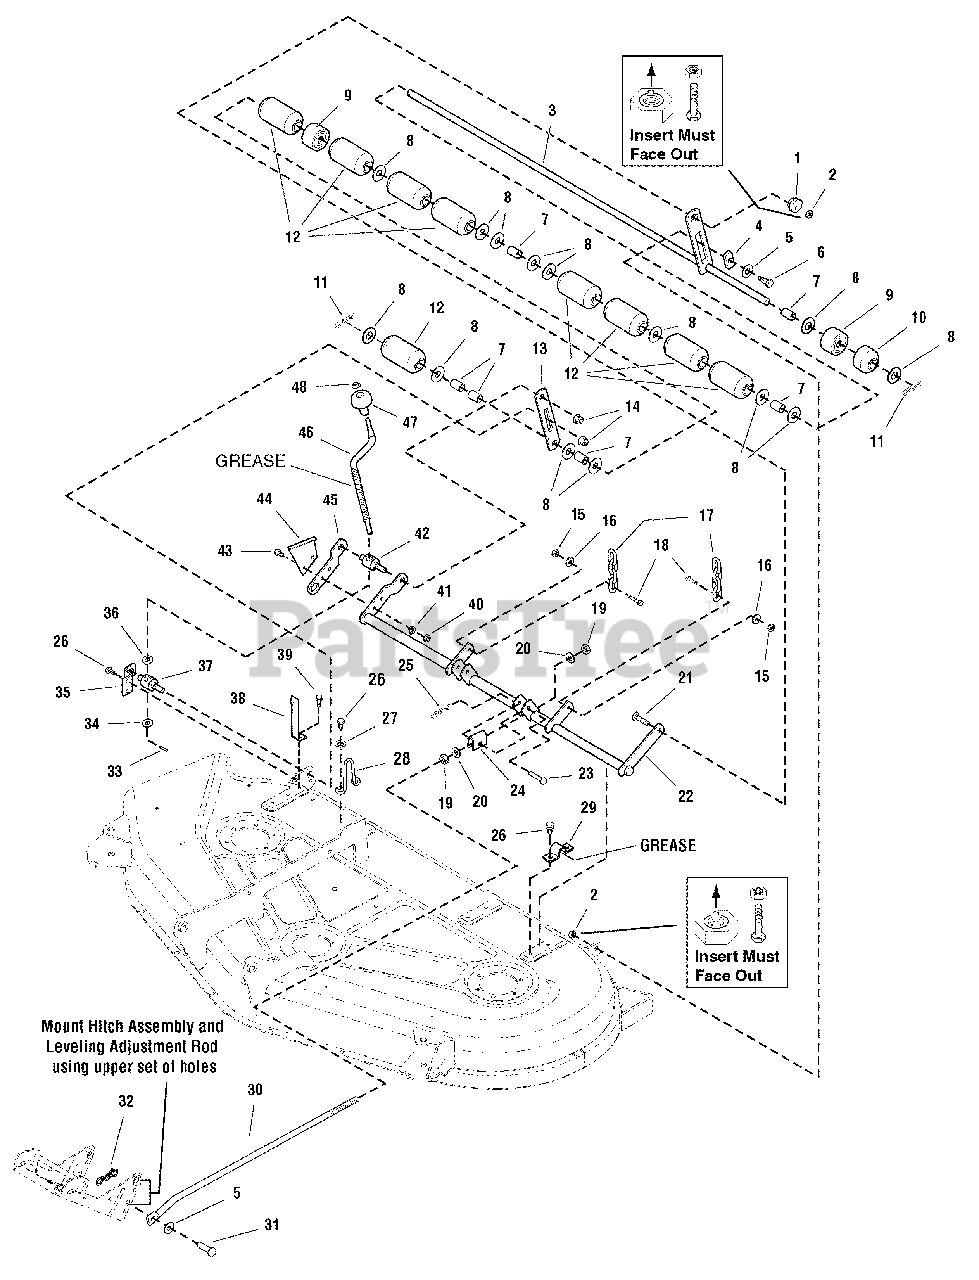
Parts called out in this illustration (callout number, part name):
1	NUT, Hex, Adjusting
2	NUT, Hex Aluminum Insert Lock, 3/8-16
3	SHAFT & BAR ASSEMBLY, Roller
4	SLIDE
5	WASHER, 1/2
6	BOLT, Shoulder, 3/8-16 x 1-5/16
7	SPACER
8	WASHER
9	ROLLER, 1 x 2-3/4 x 2, Black
10	ROLLER, Half Rounded
11	PIN, Cotter, 1/8 x 1-1/2, Black
12	ROLLER, with Bushings, Full
13	BAR
14	NUT, Hex Flange, 1/2-13
15	NUT, Hex Lock ESNA Light, 5/16-18
16	WASHER, 5/16
17	CHAIN, 4 Links, 6" Long
18	CAPSCREW, Hex Head, 5/16-18 x 1-1/2, G8
19	NUT, Hex, 5/8-11
20	WASHER, 5/8
21	CARRIAGE BOLT, 3/8-16 x 1-1/2
22	ASSEMBLY, Rocker Shaft
23	PIN, Round Head, 3/8 x 2
24	TRUNNION
25	CLIP, Hair Pin
26	CAPSCREW, Hex Washer Head, Taptite, 5/16-18 x 3/4
27	WASHER, 5/8
28	UP-STOP, Wire
29	STRAP
30	ROD, 5/8 x 29-5/8 Long
31	PIN, Yoke, 1/2
32	PIN, Bow Tie
33	PIN, Roll
34	WASHER, Detent, 1/2
35	SUPPORT, Trunnion
36	WASHER, 1/2
37	TRUNNION
38	INDICATOR, Height
39	CAPSCREW, Hex Washer Head, Taptite, 5/16-18 x 1
40	NUT, Hex, 5/16-18
41	WASHER, Lock, 5/16
42	TRUNNION, Threaded
43	CAPSCREW, Hex Head, 5/16-18 x 1-1/4
44	BRACKET, Height of Cut
45	ARM
46	CRANK, Height Adjust
47	KNOB, Spinner
48	PUSHNUT, 3/8
